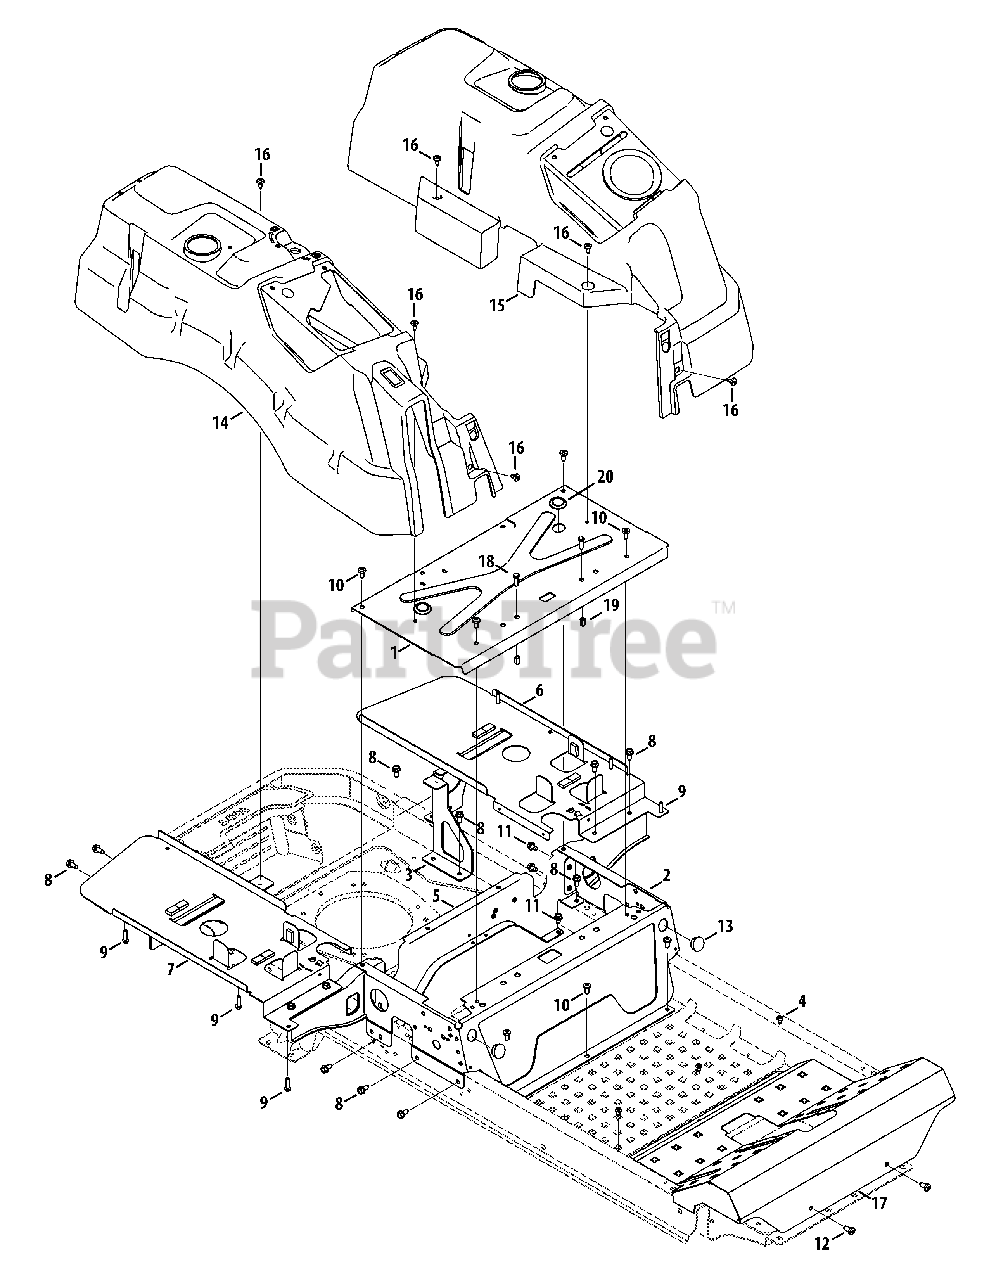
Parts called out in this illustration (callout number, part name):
1	Seatbox Plate
2	Seat Frame
3	Rear Support Bracket, LH
3	Rear Support Bracket, RH
4	Screw, 1/4-20 x .50
5	Rear Seatbox Brace
6	Tank Support Plate, LH
7	Tank Support Plate, RH
8	Hex Washer Screw, 5/16-18 x .750
9	Hex Washer Screw, 5/16-14 x 1.00
10	Self Tapping Screw, 5/16-18 x .750
11	Hex Washer Screw, 5/16-18 x .50
12	Screw, 5/16-18 x .75
13	Plastic Plug
14	RH Console
15	LH Console
16	Shoulder Screw, 1/4-20
17	Floor Board, Fab
18	Hex Cap Screw, 5/16-18 x 1.00
19	Nut, 5/16-18
20	Button Plug
